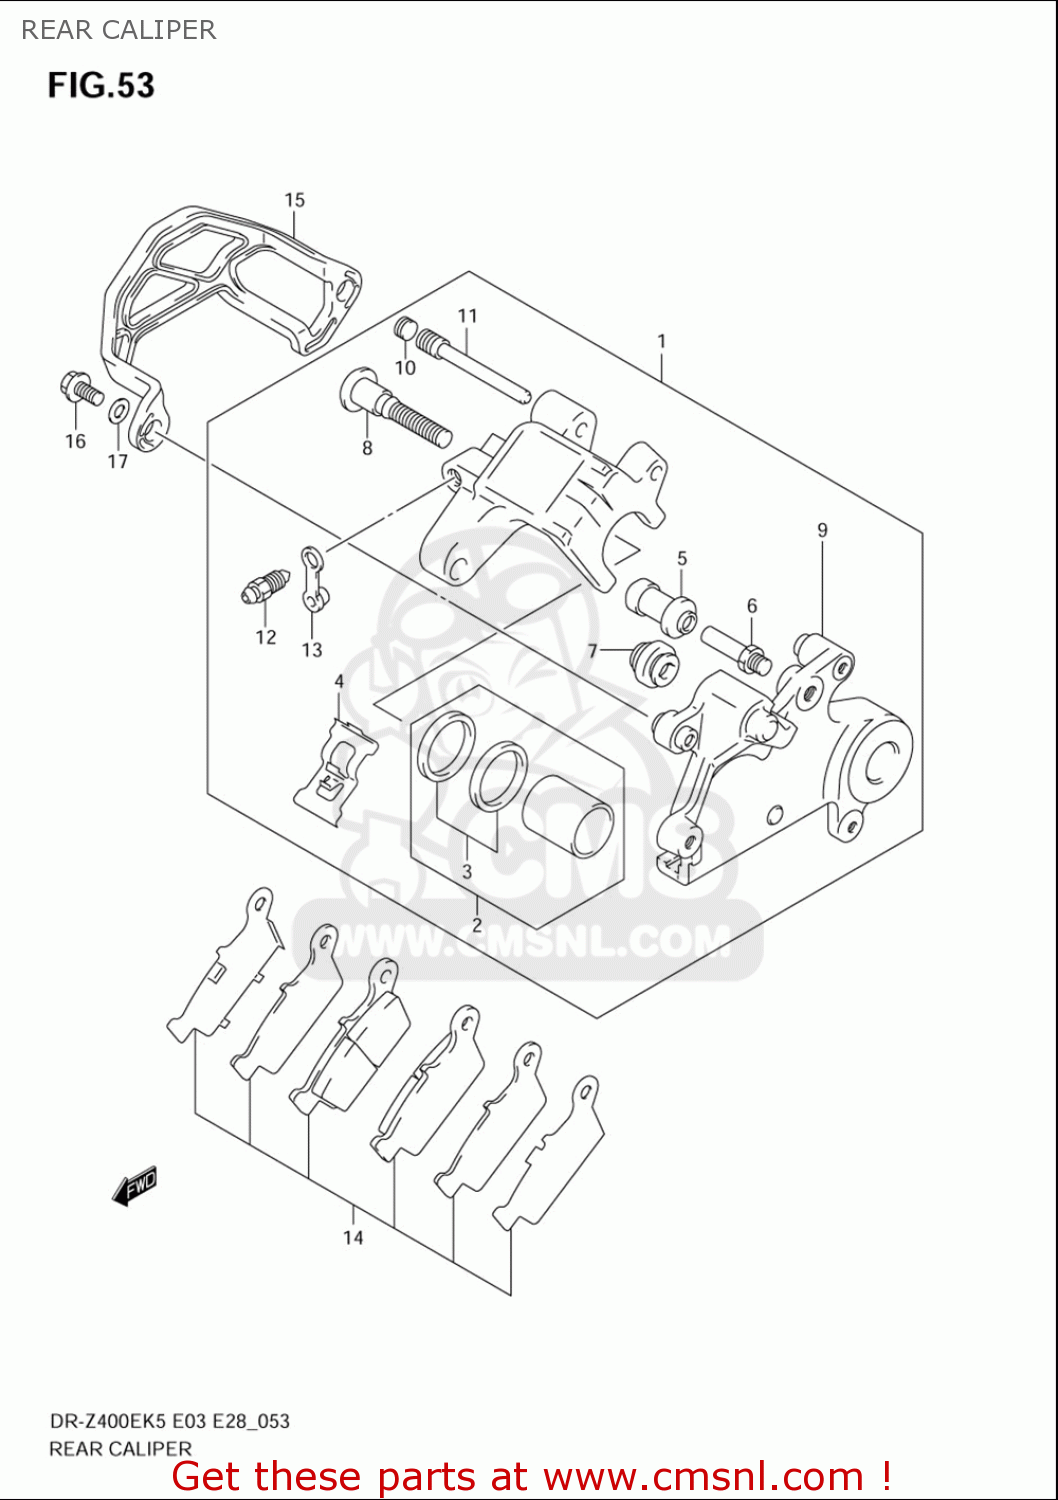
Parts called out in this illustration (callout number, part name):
1	CALIPER ASSY,RR
2	PISTON SET
3	SEAL SET,PISTON
4	SPRING,PAD
5	BOOT
6	BOLT
7	BOOT
8	PIN,BOLT
9	BRACKET
10	PLUG,PIN
11	PIN,HANGER
12	BLEEDER
13	CAP,BLEEDER
14	PAD & RETAINER SET
15	REAR CALIPER GUARD SET
16	BOLT
17	WASHER
